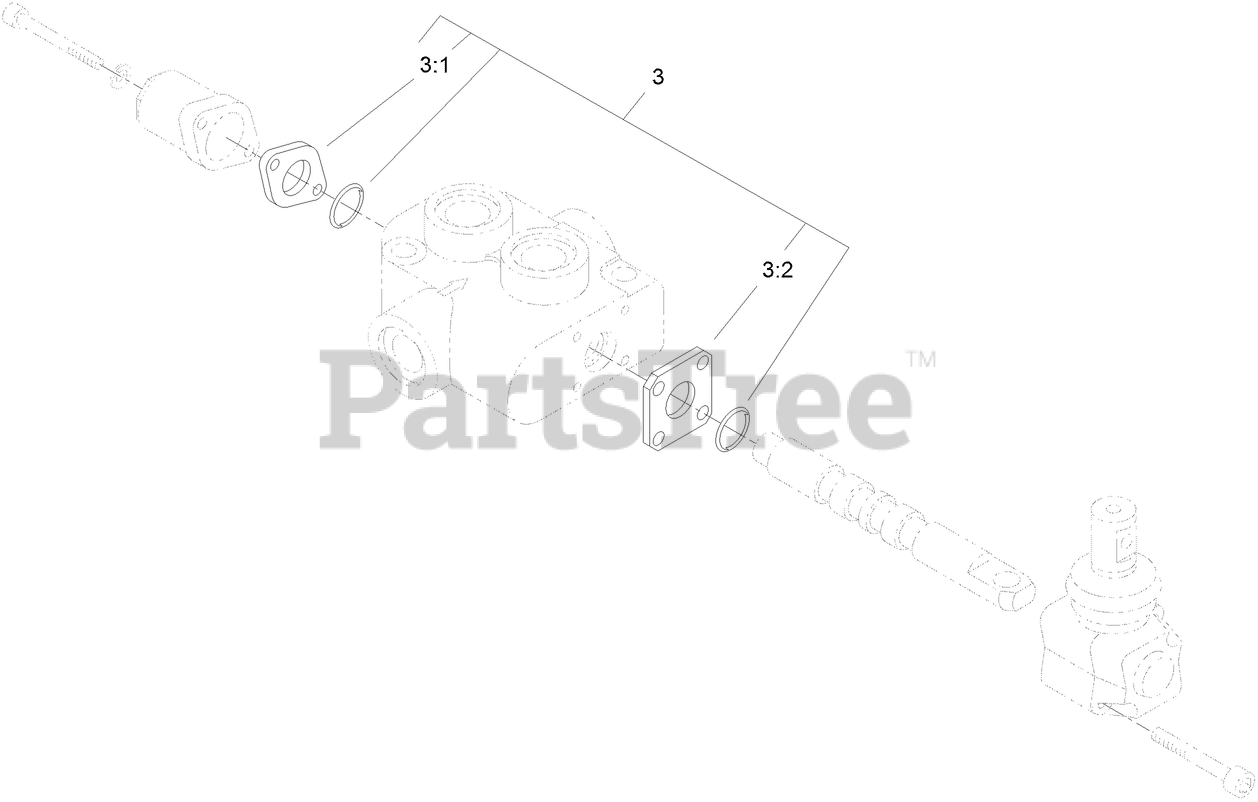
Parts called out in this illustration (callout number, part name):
3	SEAL KIT
3:1	GASKET
3:2	GASKET
